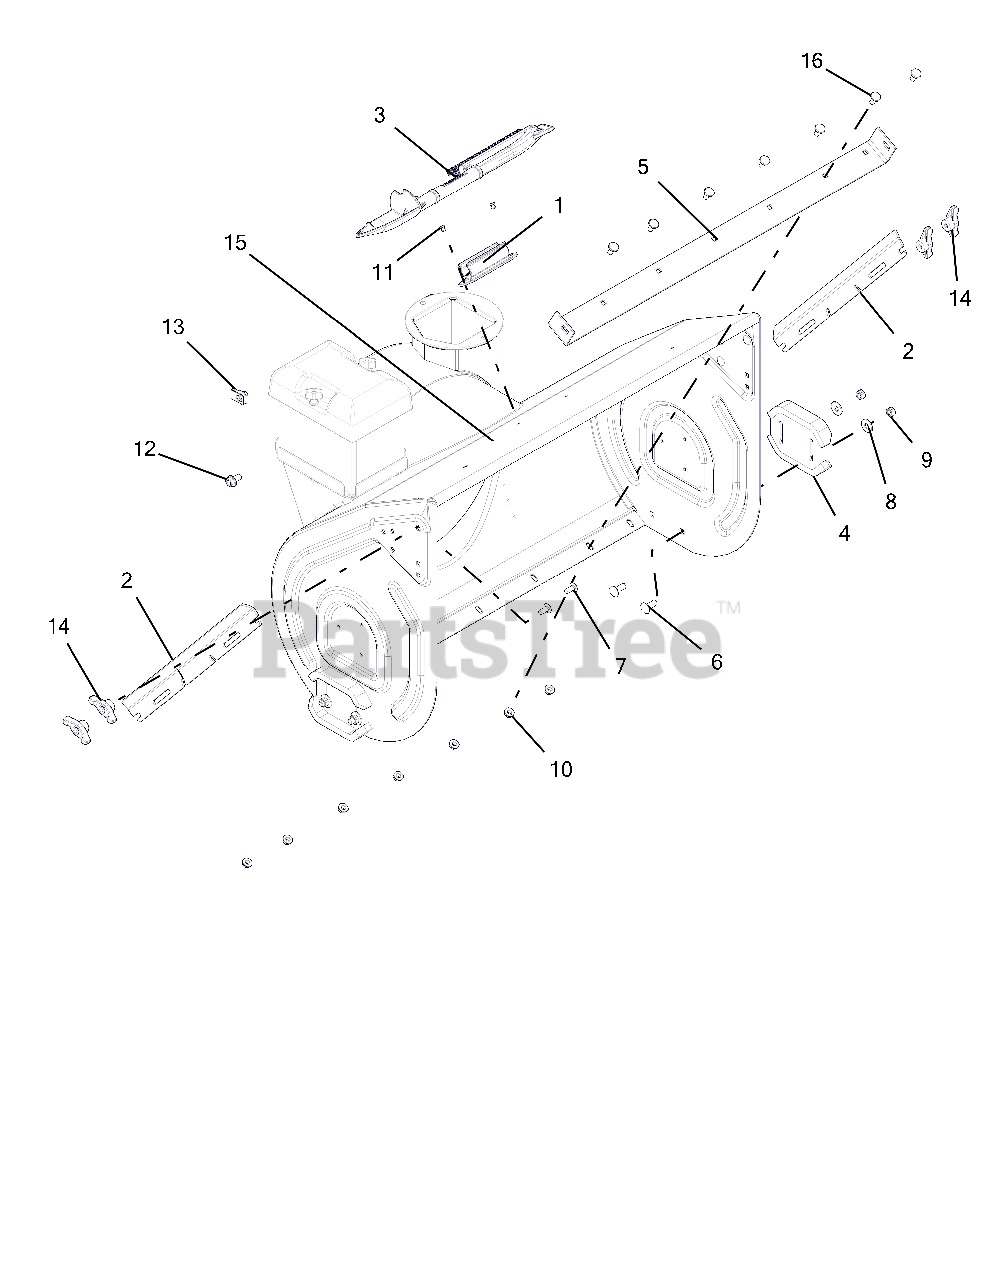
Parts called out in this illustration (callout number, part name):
1	MOUNT, SNOW CLEAN OUT
2	CUTTER, DRIFT
3	DEVICE, SNOW CLEAN OUT W/BRUSH
4	RUNNER, SKID SHOE
5	BLADE, SCRAPER-32"
6	@BLT-RDHDSHSQNK.38-16X1.0 G5YZ
7	@BLT-RHDSSQNK .31-18X.75 G5YZ
8	@WSHR-FL-STL.438X1.00X.083 YWZ
9	@NUT-LK-CTR .38-16 YWZC
10	@NUT-LK-TOP-FLG .31-18 YWZC
11	RVT-POP .187 YZ
12	BLT-SERHFWH .38-16X.75 YWZC
13	NUT-RTNR .375-16X.37
14	KNOB,WING .31-18 UNC NYL/TALC
15	BLOWER HOUSING W/DECAL 32" BAT
16	BOLT, MODIFIED HEAD CARRIAGE
